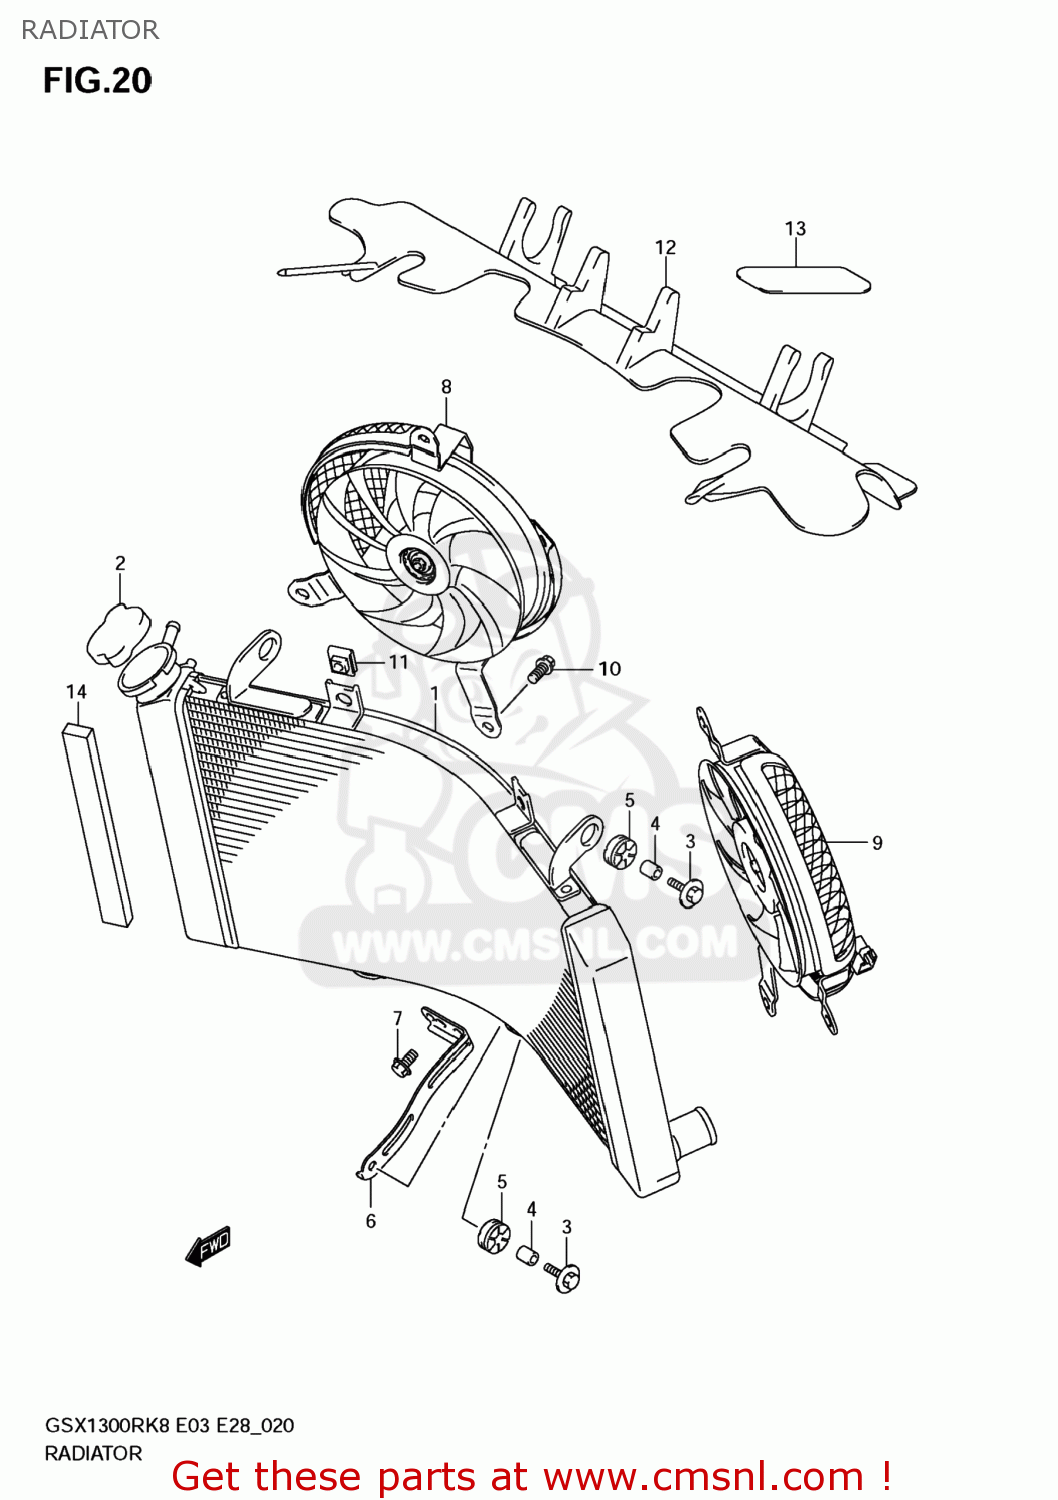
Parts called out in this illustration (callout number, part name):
1	RADIATOR ASSY,
2	CAP COMP,RADIATOR
3	BOLT(6X25)
4	SPACER(6.5X10X12)
5	CUSHION
6	BRACKET,RADIATOR
7	BOLT
8	FAN ASSY,RADIATOR,R
9	FAN ASSY,RADIATOR,L
10	BOLT,FAN ASSY
11	NUT,FAN ASSY
12	SHIELD,RADIATOR HEAT
13	TAPE,RR FENDER
14	CUSHION,UNDER COWLING
